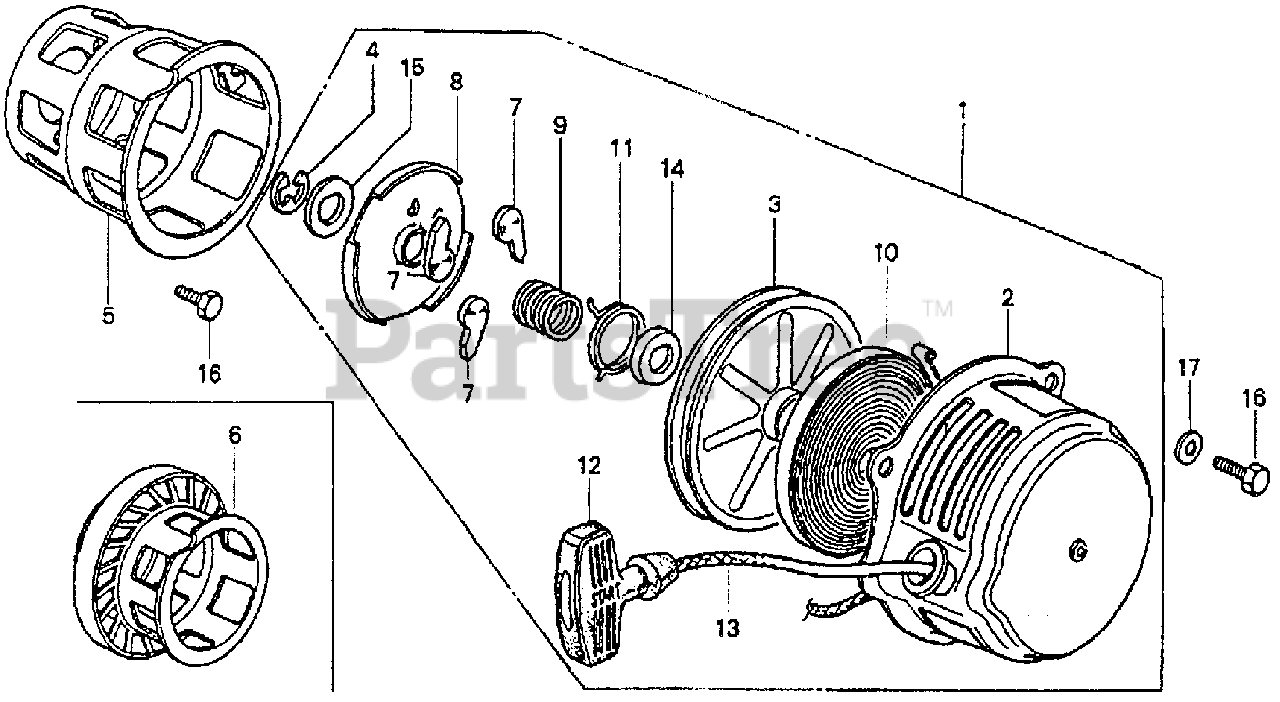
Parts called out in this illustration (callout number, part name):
1	STARTER ASSY., RECOIL *R8* (BRIGHT RED) (NOT AVAILABLE)
2	CASE, RECOIL STARTER *R8* (BRIGHT RED)
3	PULLEY, RECOIL STARTER (NOT AVAILABLE)
5	PULLEY, STARTER
7	RATCHET, STARTER
8	PLATE, FRICTION
9	SPRING, FRICTION
10	SPRING, STARTER RETURN
11	SPRING SET
12	KNOB SET, STARTER
13	ROPE, STARTER (#6X64")
16	BOLT, HEX. (6X12)
17	WASHER, PLAIN (6MM)
